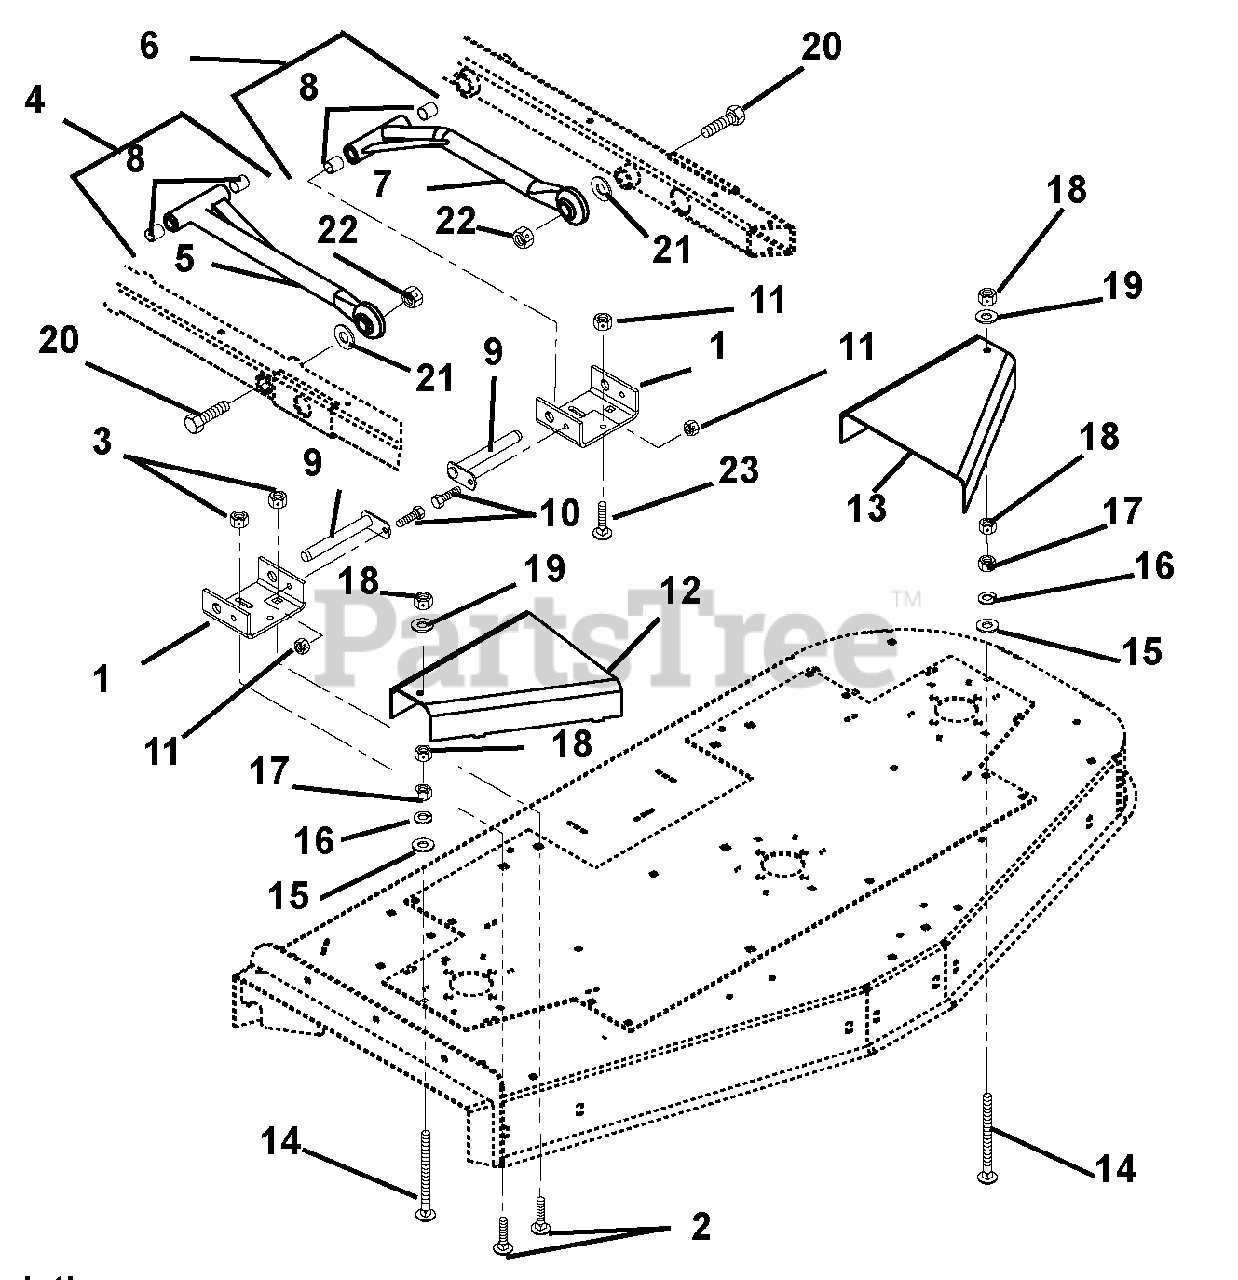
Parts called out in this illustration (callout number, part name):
1	Bracket, Mower Mounting (Rear)
2	Bolt-Round Head Square Neck .50-13 x 1.00 Grade 5
3	Nut-Locking-Center-Jam .500-13
4	Assembly, Mower Mounting Arm (Contains Items 5, 8)
5	Weldment-Mower Mounting Arm
6	Assembly, Mower Mounting Arm Left Hand (Contains Items 7,8)
7	Weldment, Mower Mount Arm
8	Bearing .75 x .875 x 1.00
9	Weldment, Mower Mounting Pin
10	Bolt-Hex .38-16 x .75 Grade 5
11	Nut-Locking-Top-Flange .38-16
12	Guard, Pulley Right Hand (016)
13	Guard, Pulley Left Hand (016)
14	Bolt-Round Head Square Neck .312-18X3.50
15	Washer-Flat-Steel .344 x .688 x .065
16	Washer-Locking .31 x .078
17	Nut-Hex .31-18
18	Nut-Locking-Center .31-18
19	Washer-Flat-Steel .344 x .688 x .065
20	Bolt,Hex .875 x 5.50 Grade 5
21	Washer-Flat-Steel .875 x 1.500 x .1196
22	Nut-Locking-Center .875-9
23	Bolt-Round Head Square Neck .38-16X.75 Grade
